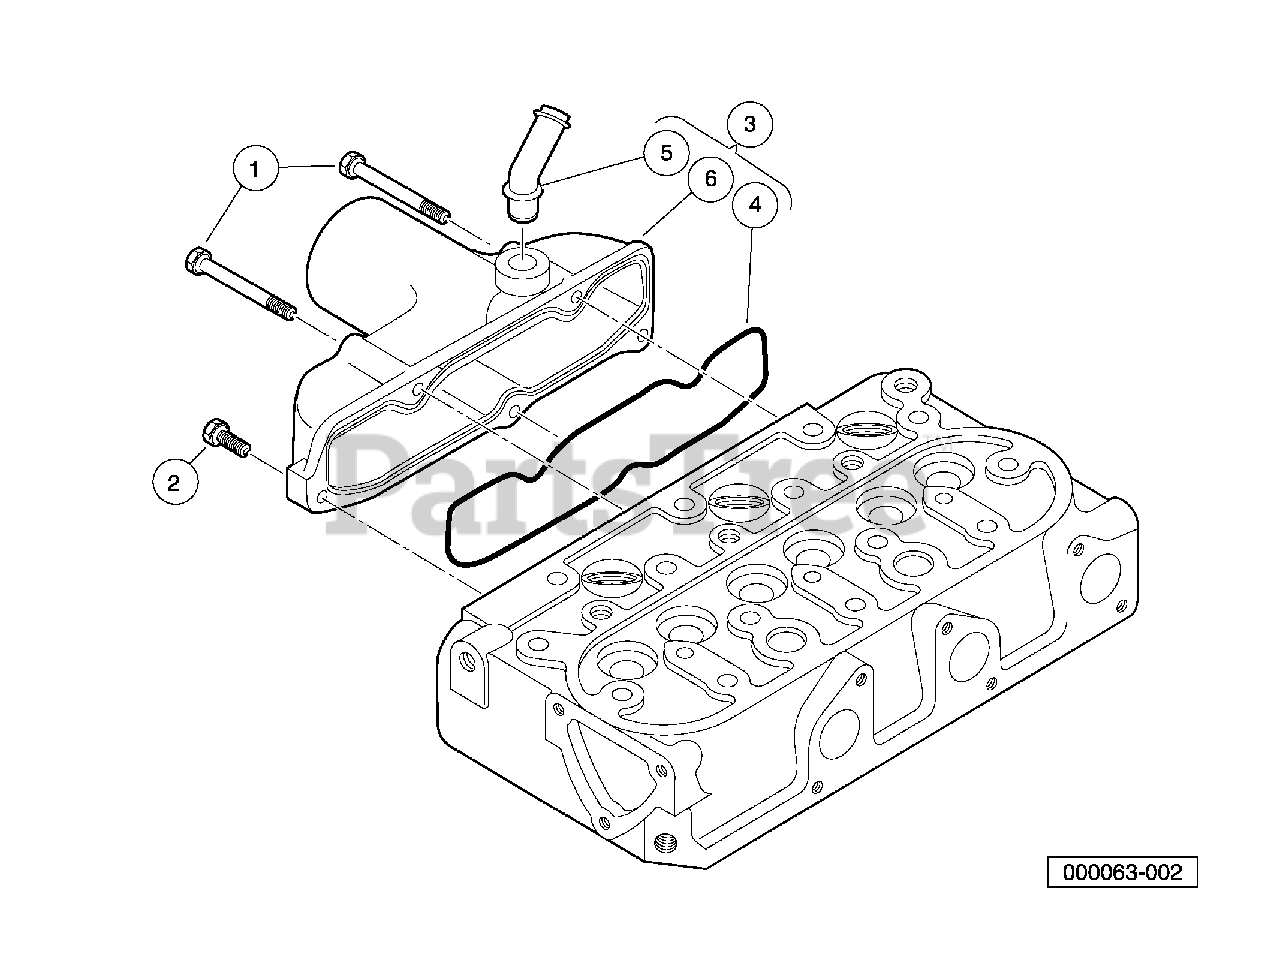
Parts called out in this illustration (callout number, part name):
1	Bolt, M6 X 1 X 45
2	Bolt, D722 Intake Manfld Lower.
3	Assembly, Intake Manifold
4	Gasket, Intake Manifold
5	Pipe, Breather
6	Manifold, Intake
